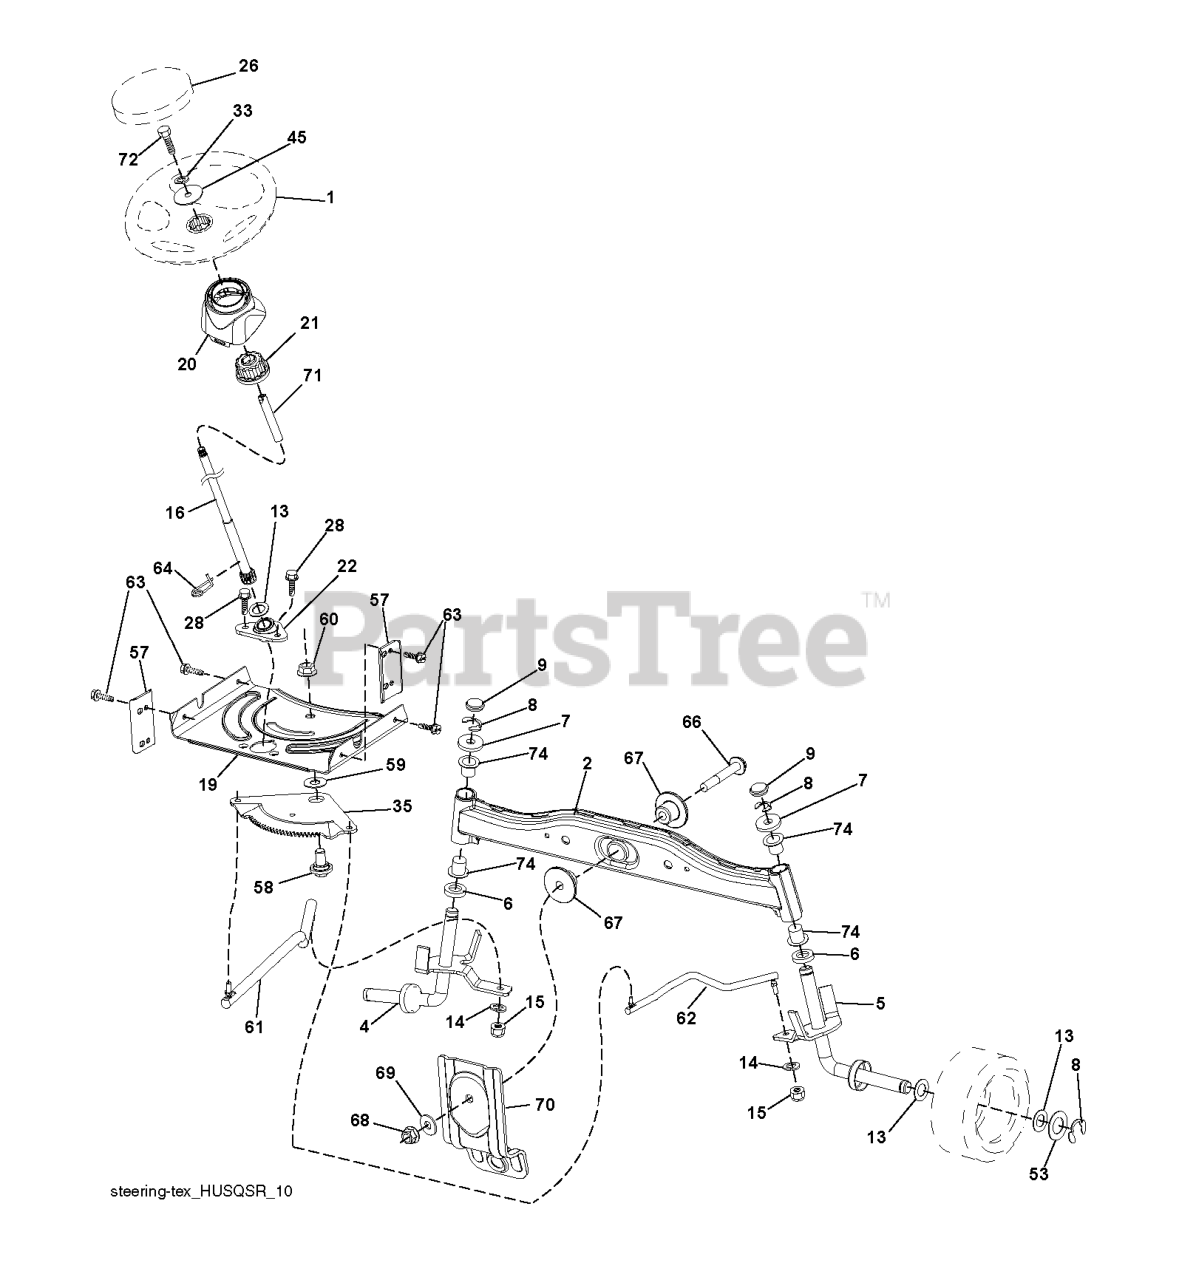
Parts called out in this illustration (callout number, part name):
1	RP WHEEL.STEER.HUSQ.PREM.OVMLD
2	AXLE HALF ASM-WELDED
4	SPINDLE.WELDED.LH.15"TEX
5	SPINDLE.WELDED.RH.15"T
6	THRUST WASHER
9	CAP.SPINDLE.BLACK
14	WASHER, LOCK 3/8
15	NUT CROWNLOCK 3/8-24
16	SHAFT.STEER.3/4.PLATED.TEX
19	PLATE.STEER.DDL.NLT/NG
20	BOOT, STEERING
21	ADAPTER, WHEEL STNG..
22	STEERING.SUPT.LOWER.
26	RP INSERT.CAP.WHL.STRG.HUSQ.
28	SCREW, 3/8-16X3/4
33	WASHER.LOCK.HVY.HLCL.SPR.5/16
35	GEAR.SECTOR.PLATE.DDL.
45	WASHER.11/32
53	WASHER.HARDENED
57	BRACKET.UPSTOP.TEX
58	BOLT.SHOULDER.SECTOR.P
59	WASHER.THURST.SECTOR.S
60	NUT FLANGE LOCK 5/8-11
61	DRAGLINK.LH.BALLSTUD.D
62	DRAGLINK.RH.BALLSTUD.D
63	SCREW
64	RETAINER.CLIP.SPRING.S
66	BOLT HEX FGHD 7/16-14 X 3 SERR
67	BUSHING.PM.FRONT AXLE
68	NUT.LOCK.FLANGE.7/16
69	WASHER.1.5X.505X.118
70	BRKT.DECK.SUSPENSION.F
71	SHAFT.EXTEN.STRG.SPLINE
72	BOLT 5/16-18 X 4 W/PATCH
74	BRNG T
